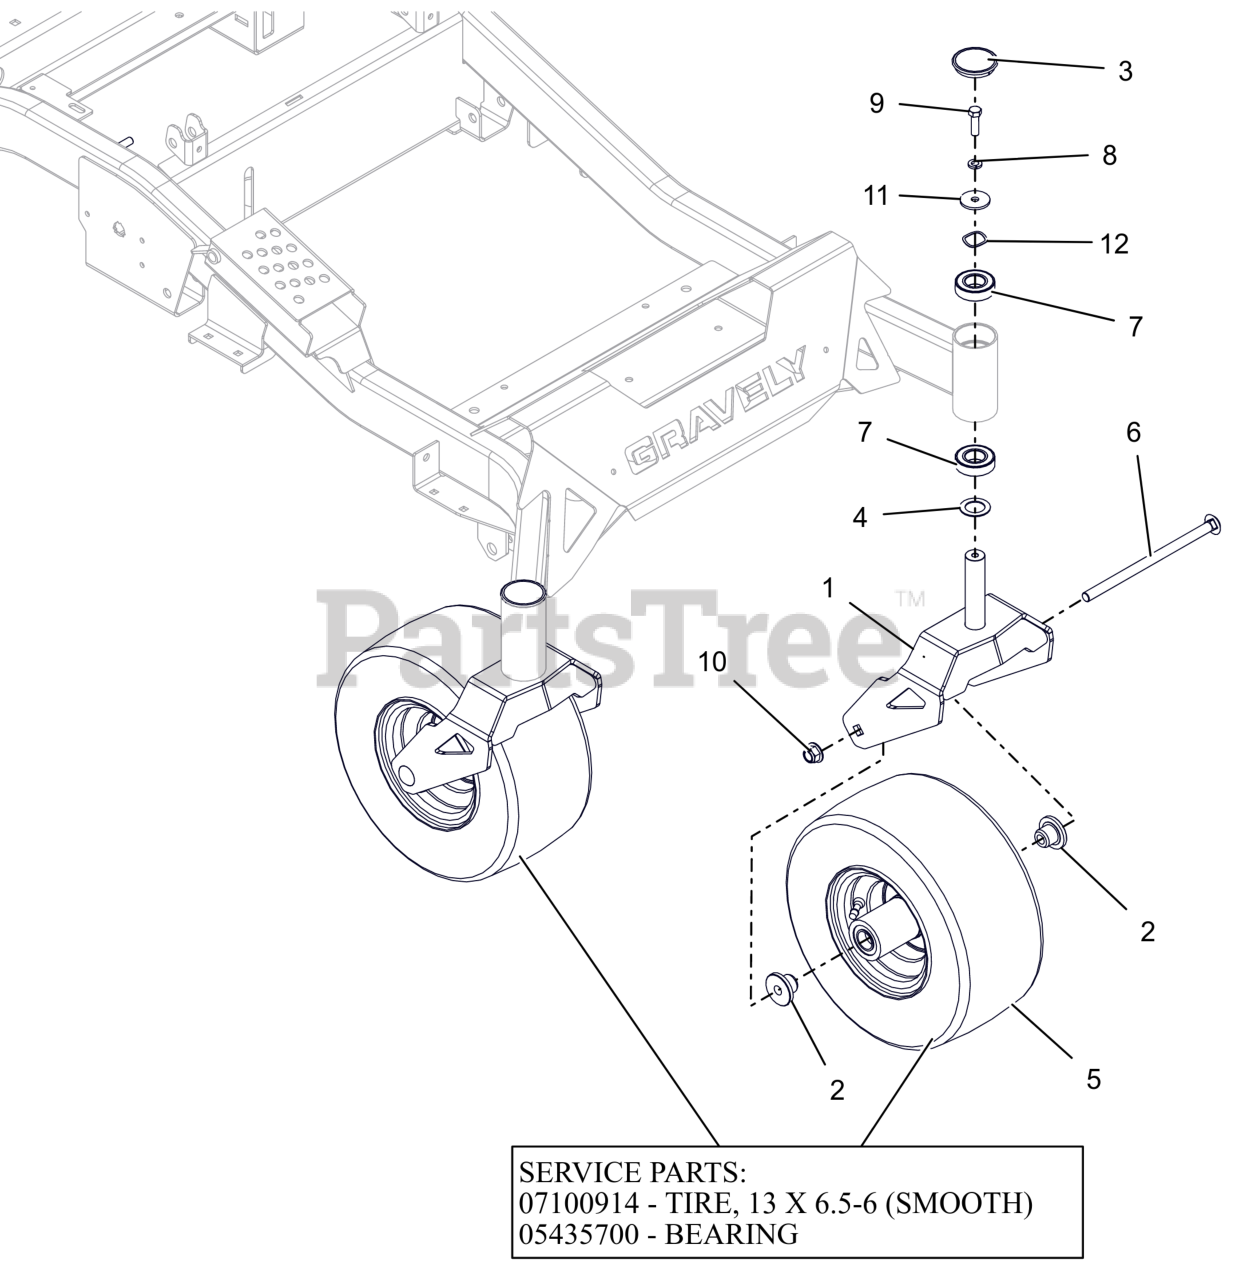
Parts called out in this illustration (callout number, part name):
1	WLDMT, CASTER FORK-HD (RED)
2	SPACER, FRONT WHEEL
3	CAP, DUST
4	WSHR-HRD-THRS 1.007X1.542X.062
5	ASM, WHL/TIRE 13X6.50-6
5	TIRE, 13X6.50-6 SMOOTH
5	BRG, 25MM ID X 52MM OD X 15MM
6	BTL,RHSN .500-13 X 9 G5 ZCC
7	BRG,BALL 1.00X2.00X.563(1641)
8	WSHR, LK-HVY .375X.115 ZCC
9	BLT, HEX .38-16X1.25 G5 ZCC
10	NUT,NYL-FLG .50-13 GF ZCC
11	WSHR, FLT .380X1.50X.125 ZCC
12	WSHR-WAVE 1.0X1.25X.028 .145FH
